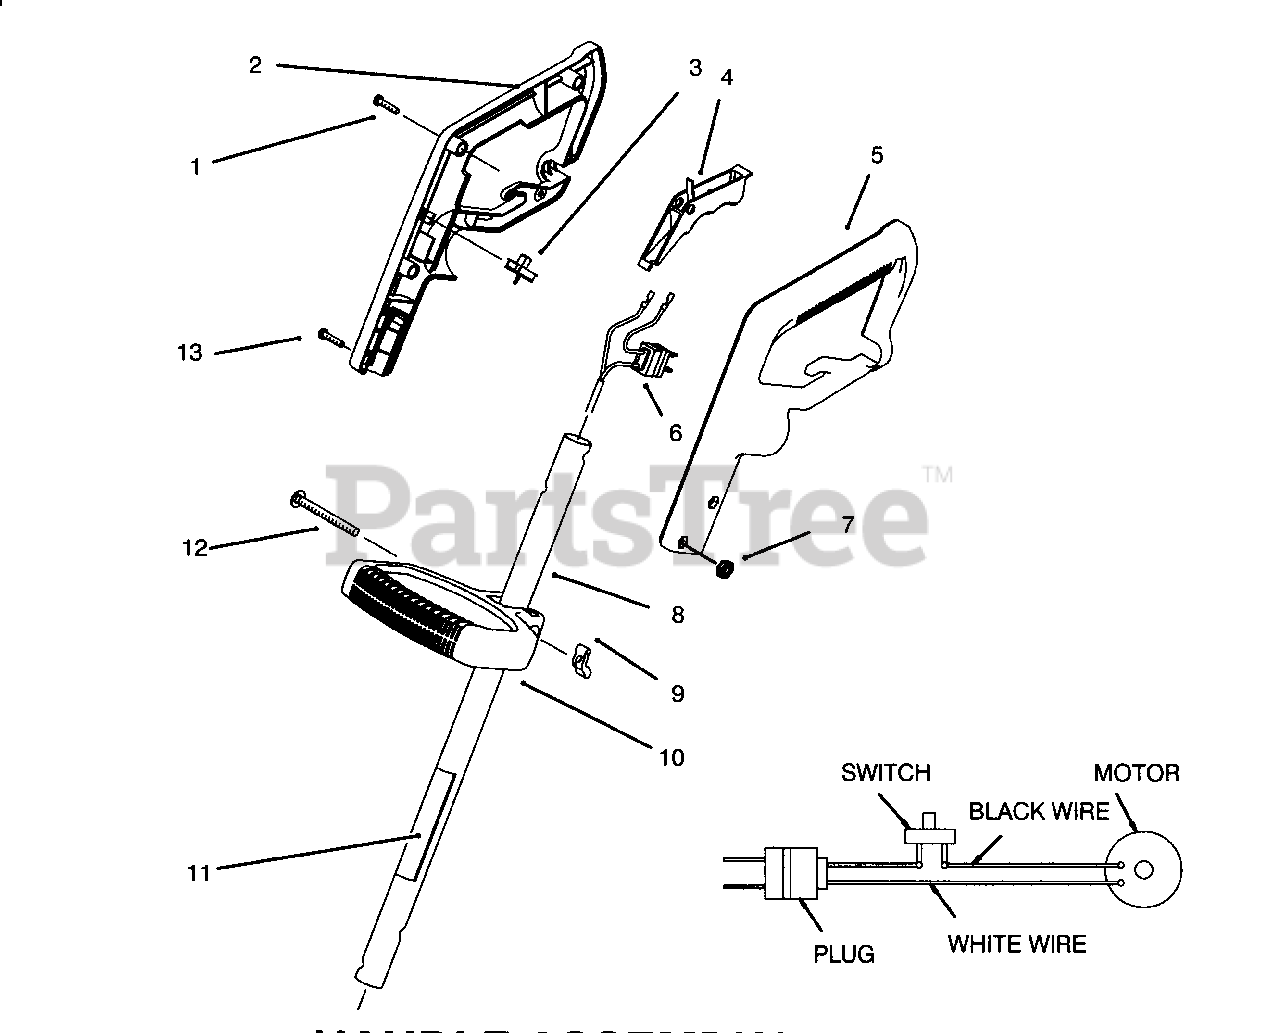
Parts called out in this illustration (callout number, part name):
1	Screw-Pan Hd Tapping
2	Grip-Hand R.H.
3	Switch-Single Speed
5	Grip-Hand L.H.
6	Harness-Wire
7	Nut-Lock
8	Tube Assembly (Incl. Ref. #11)
10	Handle-Mid
11	Decal-Safety
12	Screw-Carriage
13	Screw-Pan Hd.
